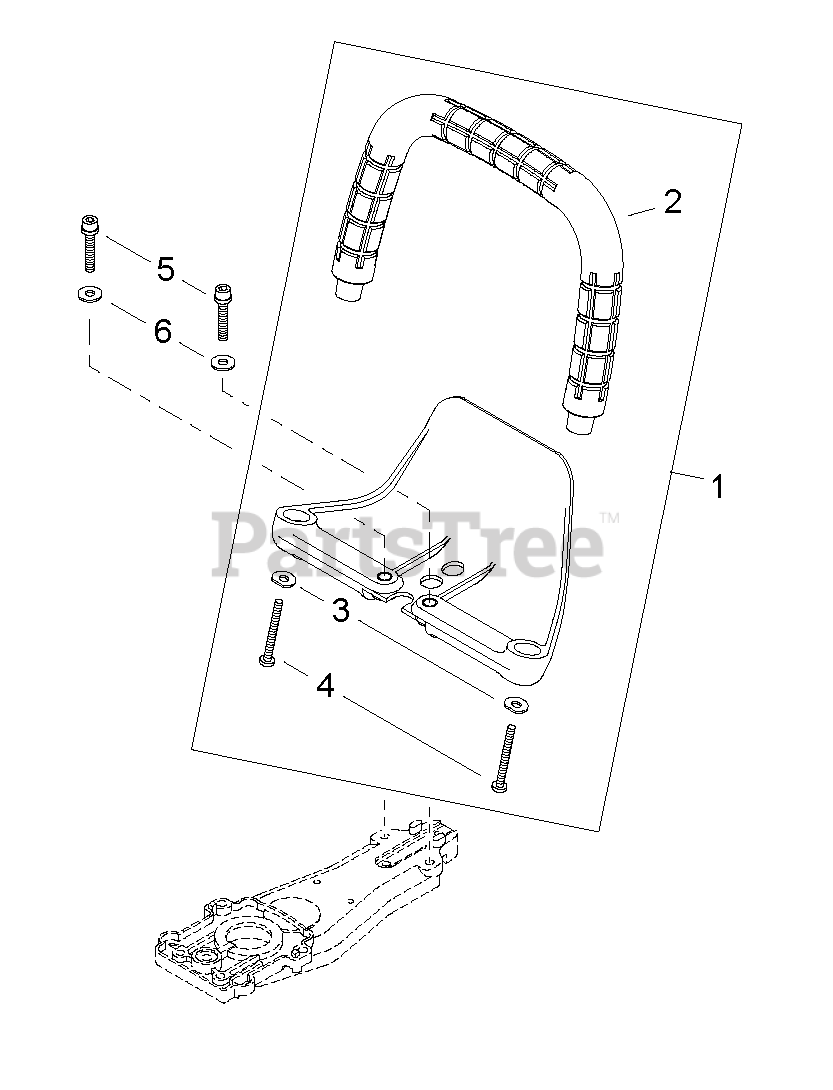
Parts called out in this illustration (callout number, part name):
1	HANDLE ASSY, FRONT
2	HANDLE, FRONT
4	BOLT, TAPPING 5
5	BOLT M6×35
6	WASHER Ø16ר6.5×1.6 MM
